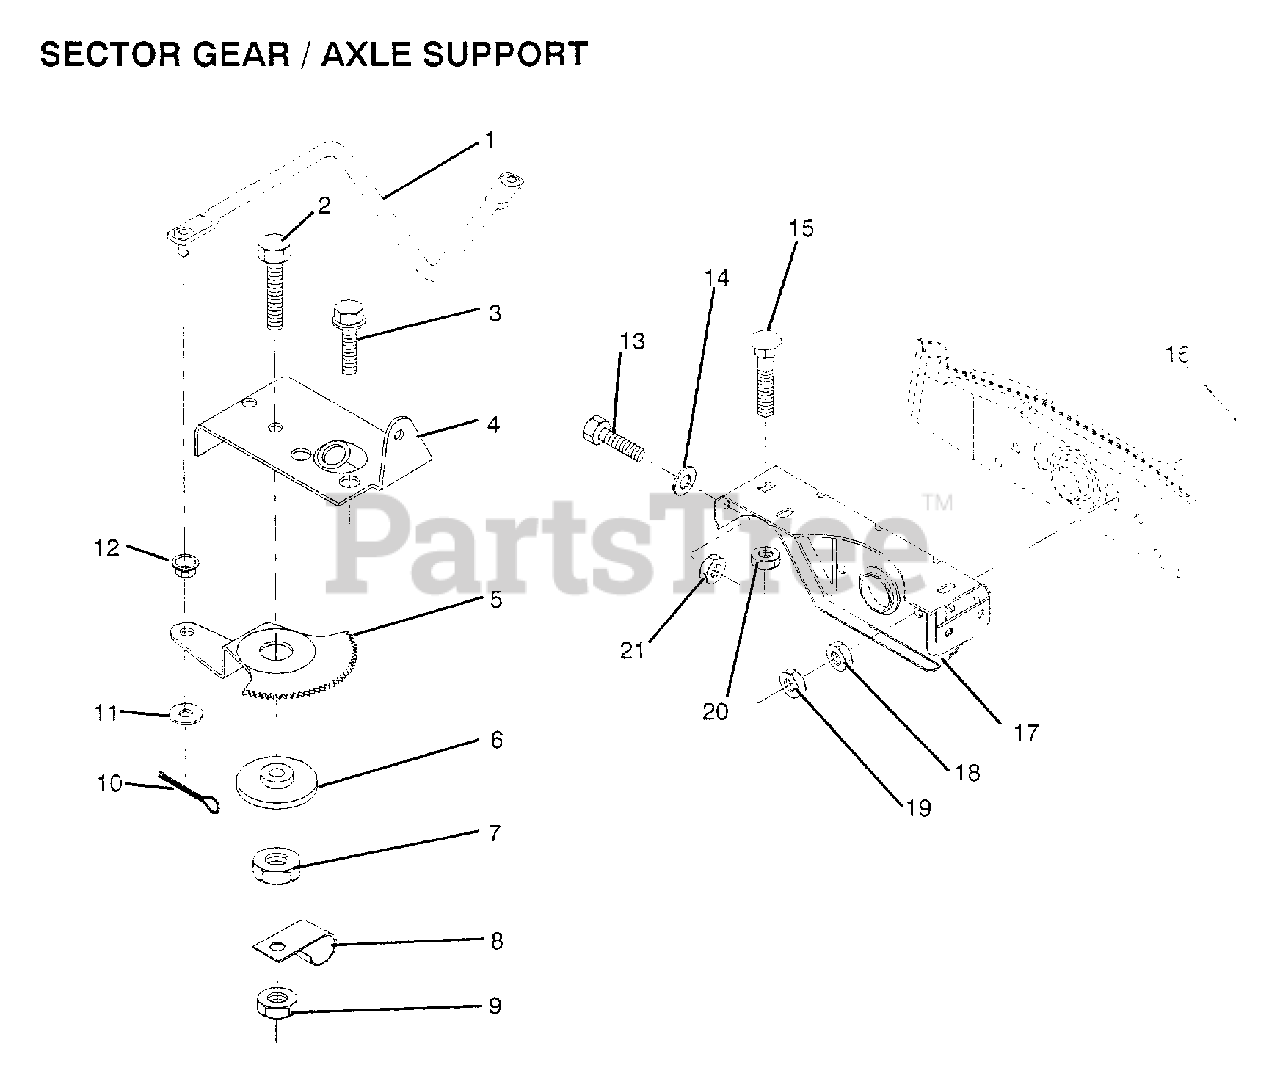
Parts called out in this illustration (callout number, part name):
2	"BOLT,HEX"
3	SCREW LT
4	"PLATE,STR SUPT"
5	GEAR SECTOR
6	BUSHING
7	NUT
8	CLIP INSULATOR
9	NUT LTV
10	COTTER PIN
11	WASHER
12	BUSHING.DRAGLINK
13	BOLT
14	WASHER
15	BOLT
16	BOLT
17	"SUPT,FRT AXLE"
18	NUT.HEX.3/8-16UNC
19	LOCKNUT
